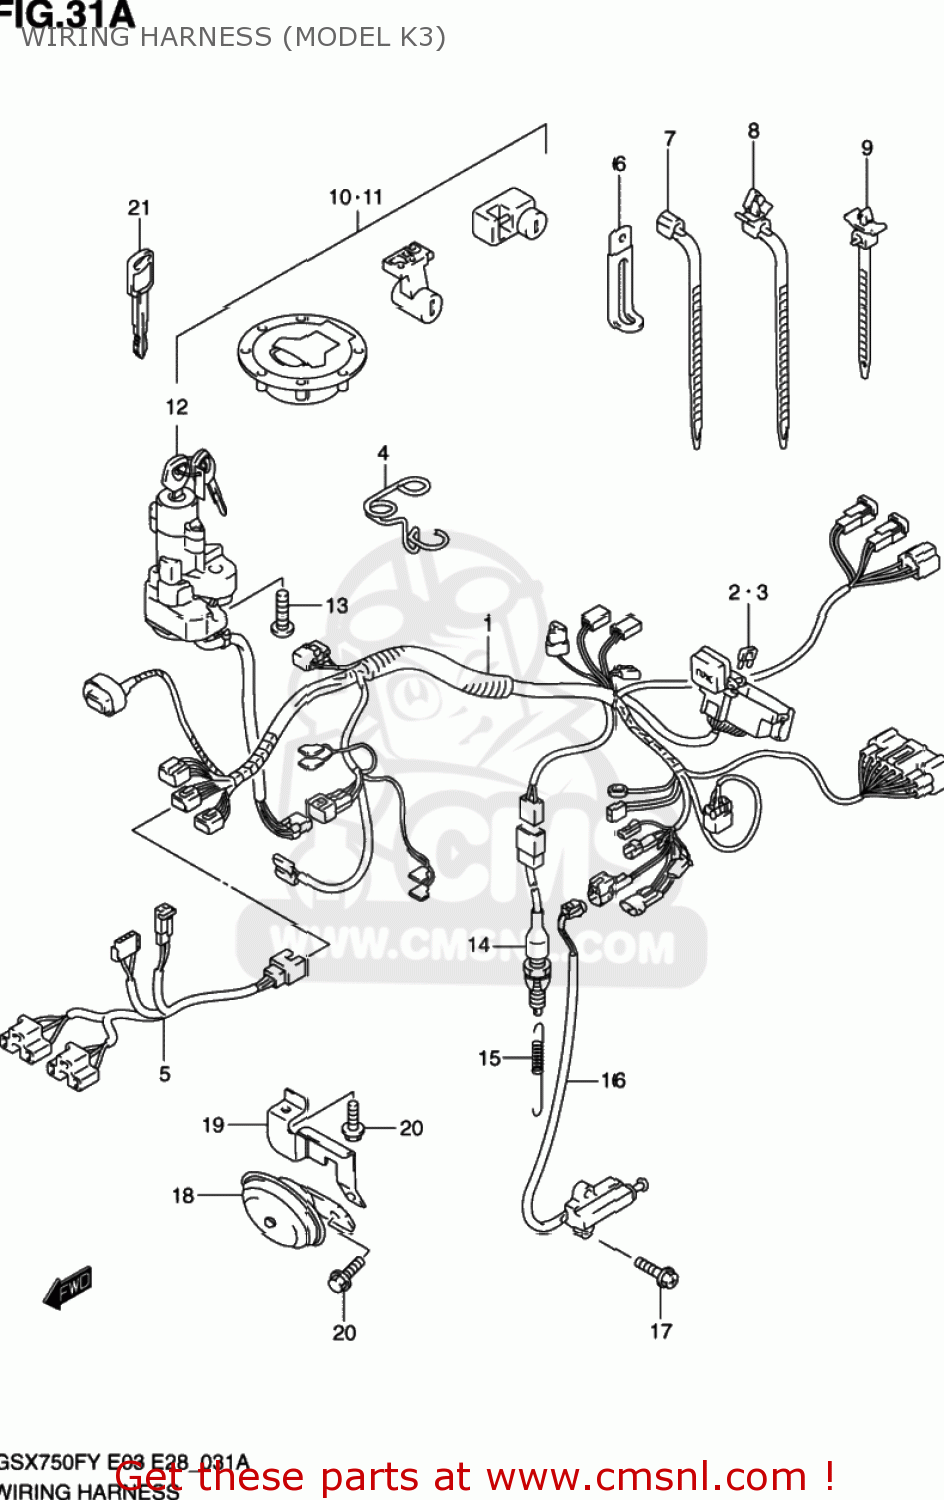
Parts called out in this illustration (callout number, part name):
1	HARNESS,WIRING
2	FUSE(10A)
3	FUSE(15A)
4	GUIDE,WIRING HARNESS
5	HARNESS,WIRING NO.2
6	WIRE,LEAD
7	CLAMP(L:135)
8	CLAMP(L:125)
9	CLAMP(L:90)
10	LOCK SET
11	LOCK SET
12	LOCK ASSY,STEERING
13	BOLT(8X20)
14	SWITCH ASSY,STOP LAMP
15	SPRING
16	SWITCH ASSY,SIDE STAND
17	SCREW
18	HORN ASSY
19	BRACKET,HORN
20	BOLT
21	KEY,BLANK
